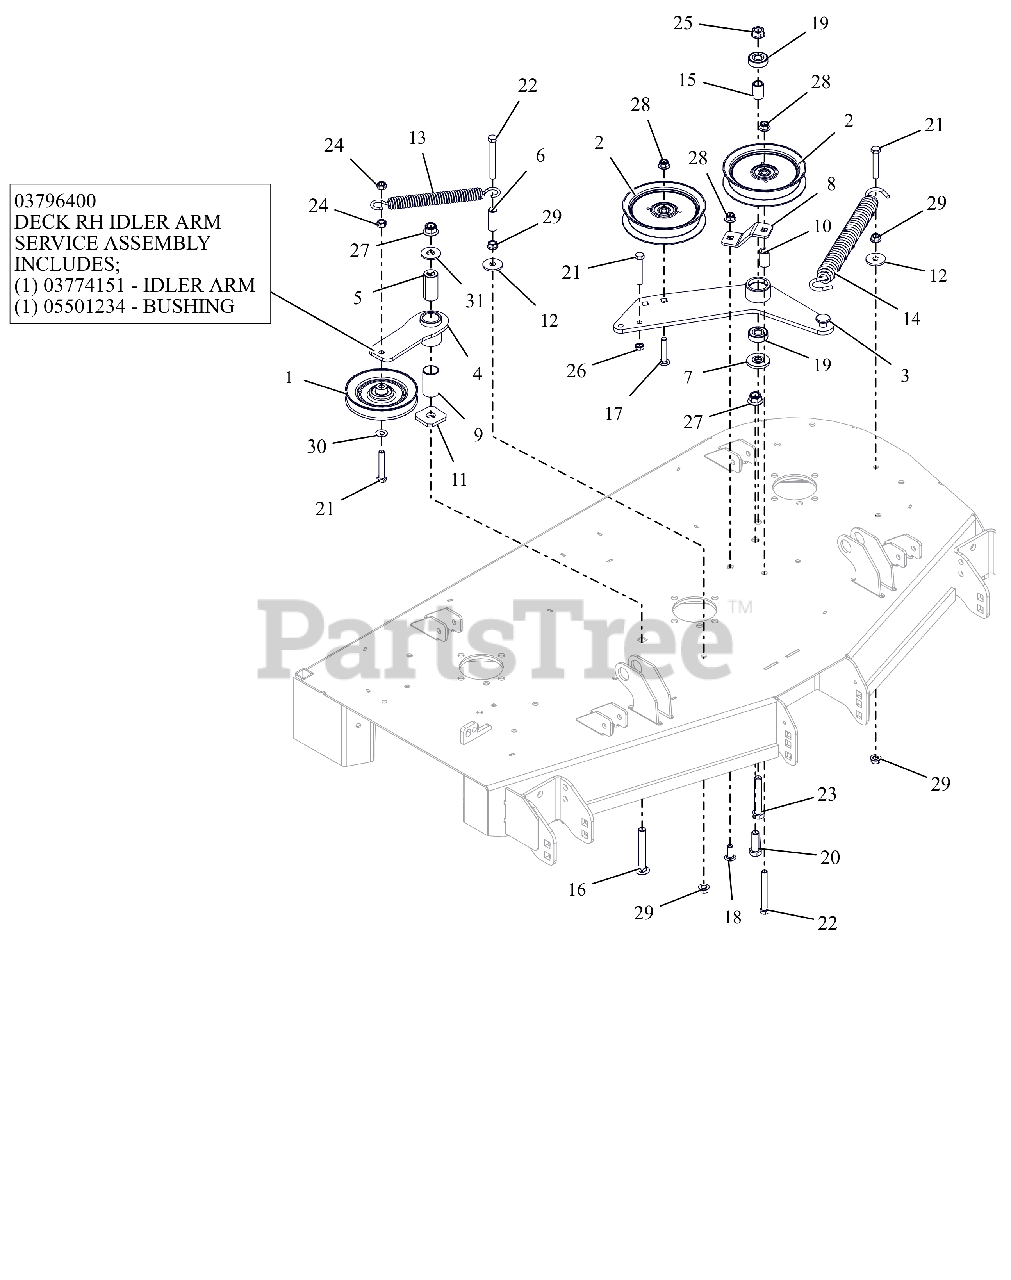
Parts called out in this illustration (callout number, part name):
1	IDLER, V-5.00"
2	IDLER, FLAT 5.00"
3	DECK PTO IDLER ARM WLDMT - BLK
4	WMT, IDLER ARM - BLACK
4	ASM, IDLER ARM (DECK)
4	BSHG, 1.00X1.125X1.937
5	BSHG, SPCR .502X.997X2.03 PM
6	SPACER, .375IDX.625ODX1.66 PM
7	SPACER, IDLER ARM
8	PTO FIXED IDLER MTG BRKT-ORG
9	BSHG, 1.00X1.125X1.937
10	BUSHING, SLV .380X.750X1.190
11	WSHR-FLT .640X1.75X.250
12	WSHR-FL-STL .406X1.375X.135 YZ
13	SPRING, EXTENSION
14	SPRING, EXTENSION
15	SPACER .510 X .75 X 1.1485
16	@BLT-RDHDSQNK .50-13X3.50 G5YZ
17	BLT-RDHDSQNK .38-16X2.00 SHTYW
18	@BLT-RDHDSHSQNK.38-16X1.0 G5YZ
19	BRG-BALL .500X1.38X.437
20	@BLT-HEX .50-13X1.50 GR5 YWZC
21	@BLT-HEX .38-16X2.25 GR5 YWZC
22	@BLT-HEX .38-16X3.25 GR5 YWZC
23	@BLT-HEX .50-13X3.00 GR5 YWZC
24	@NUT-LK-CTR .38-16 YWZC
25	NUT-LK-CTR-FLG .50-13 YWZC
26	NUT-HEX-JAM .375-16 YWZC
27	@NUT-LK-NYL-FLG .50-13 YWZC
28	@NUT-LK-NYL-FLG .38-16 YWZC
29	@NUT-SPNLK-FLG .375-16 YWZC
30	@WSHR-FL-STL.406X.812X.065 YWZ
31	@WSHR-FL-STL.563X1.38X.109YWZC
